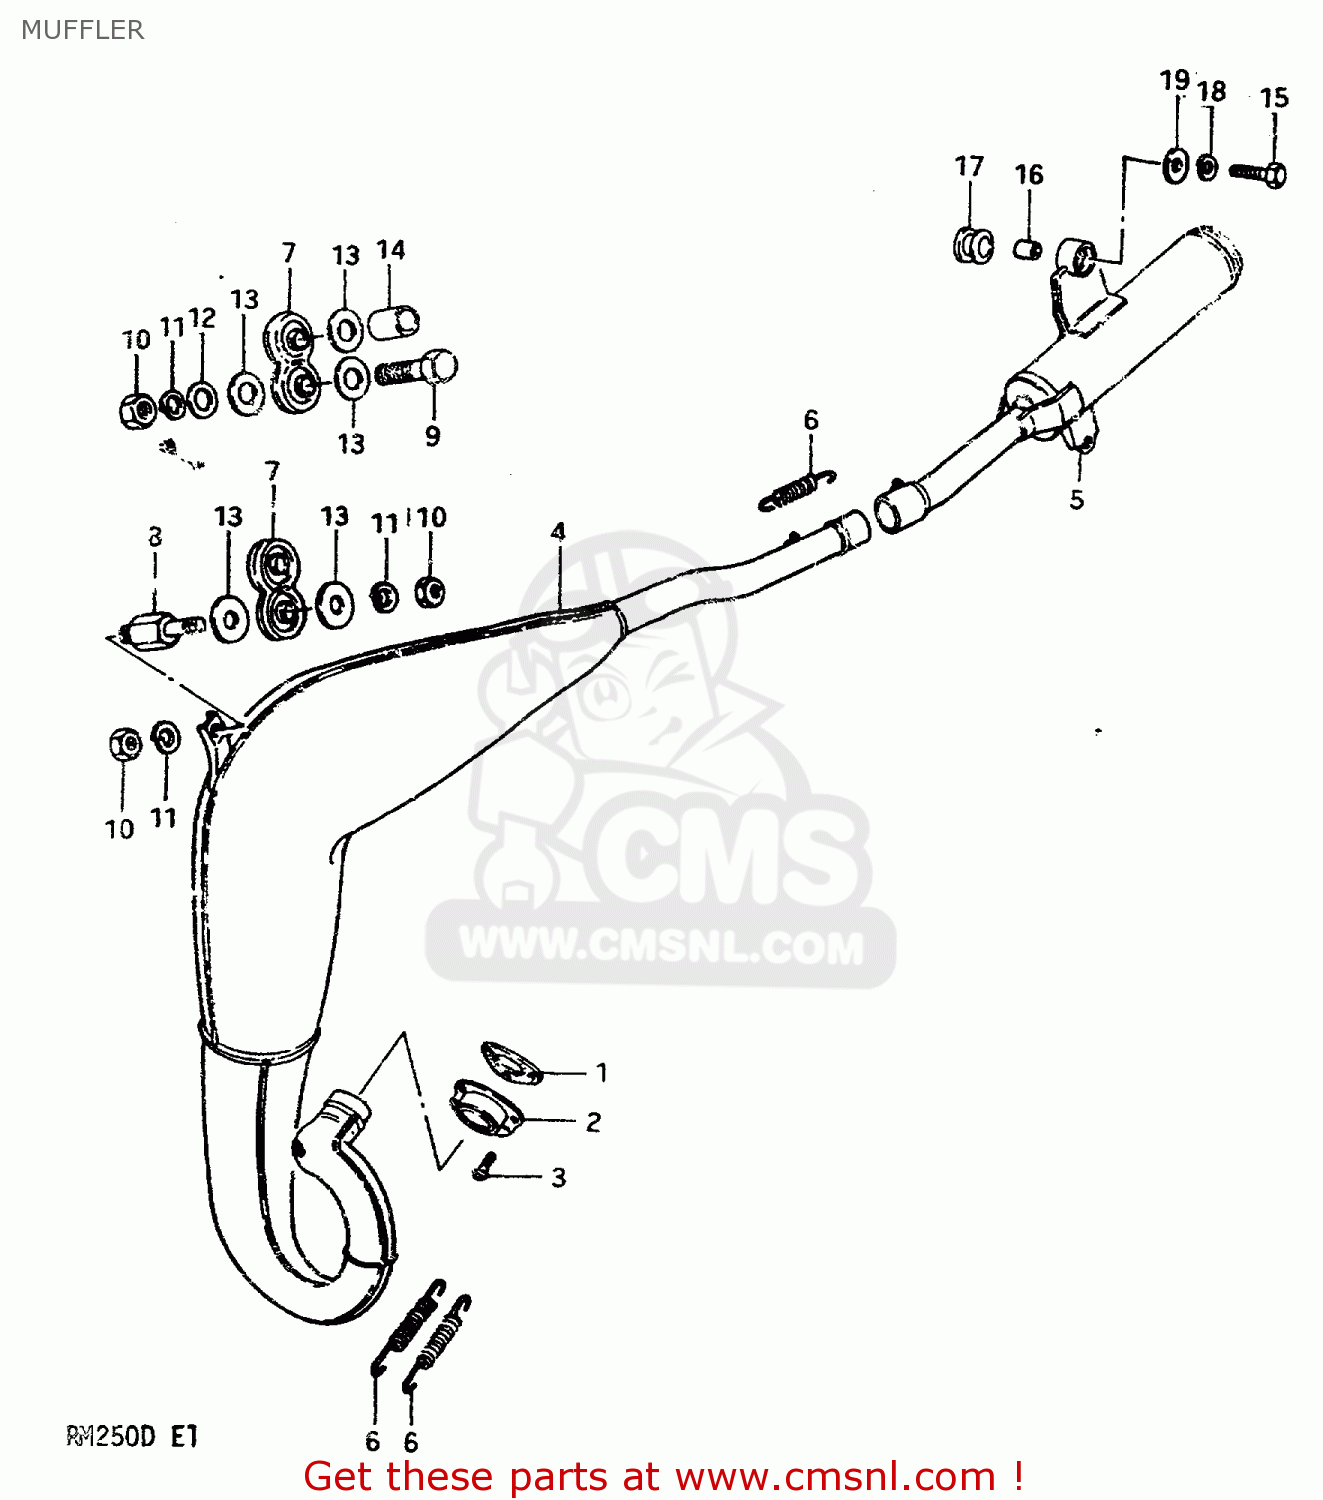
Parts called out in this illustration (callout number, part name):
1	GASKET,EXHAUST PIPE (MCA)
2	FLANGE,EXHAUST PIPE
3	SCREW
4	BODY,MUFFLER,FIRST
5	BODY,MUFFLER,SECOND
6	SPRING
7	DAMPER,MUFFLER
8	STUD
9	BOLT
10	NUT
11	LOCK WASHER
12	WASHER
13	WASHER
14	SPACER (8.6X16X23.5)
15	BOLT(8X32)
16	SPACER (8.6X12X17.5)
17	CUSHION
18	LOCK WASHER
19	WASHER (8.5X29X1.6)
